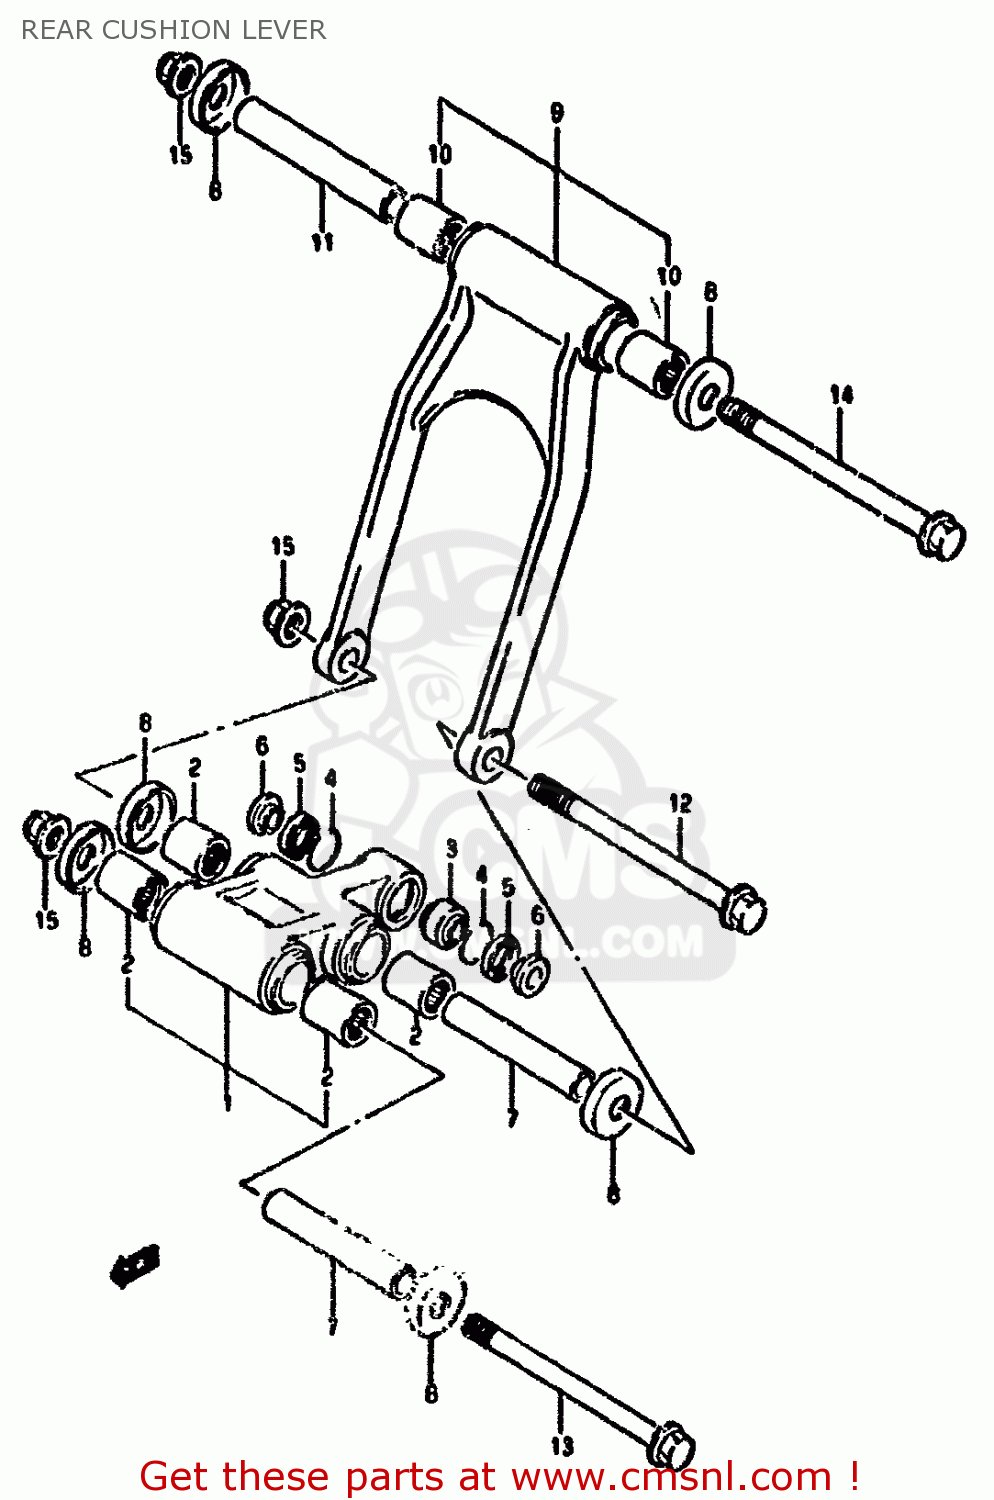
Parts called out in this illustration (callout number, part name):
1	LEVER SET,REAR CUSHION
2	BEARING(17X24X30)
3	BEARING,RR CUSHION LEVER
4	RING,STOPPER
5	DUST SEAL,RR CUSHION LEVER RR
6	SPACER
7	SPACER,REAR CUSHION LEVER
8	COVER,THRUST
9	ROD SET,REAR CUSHION,LEFT
10	BEARING(17X24X30)
11	SPACER,REAR CUSHION ROD
12	BOLT L:145
13	BOLT L:135
14	BOLT(12X155)
15	NUT 12MM
